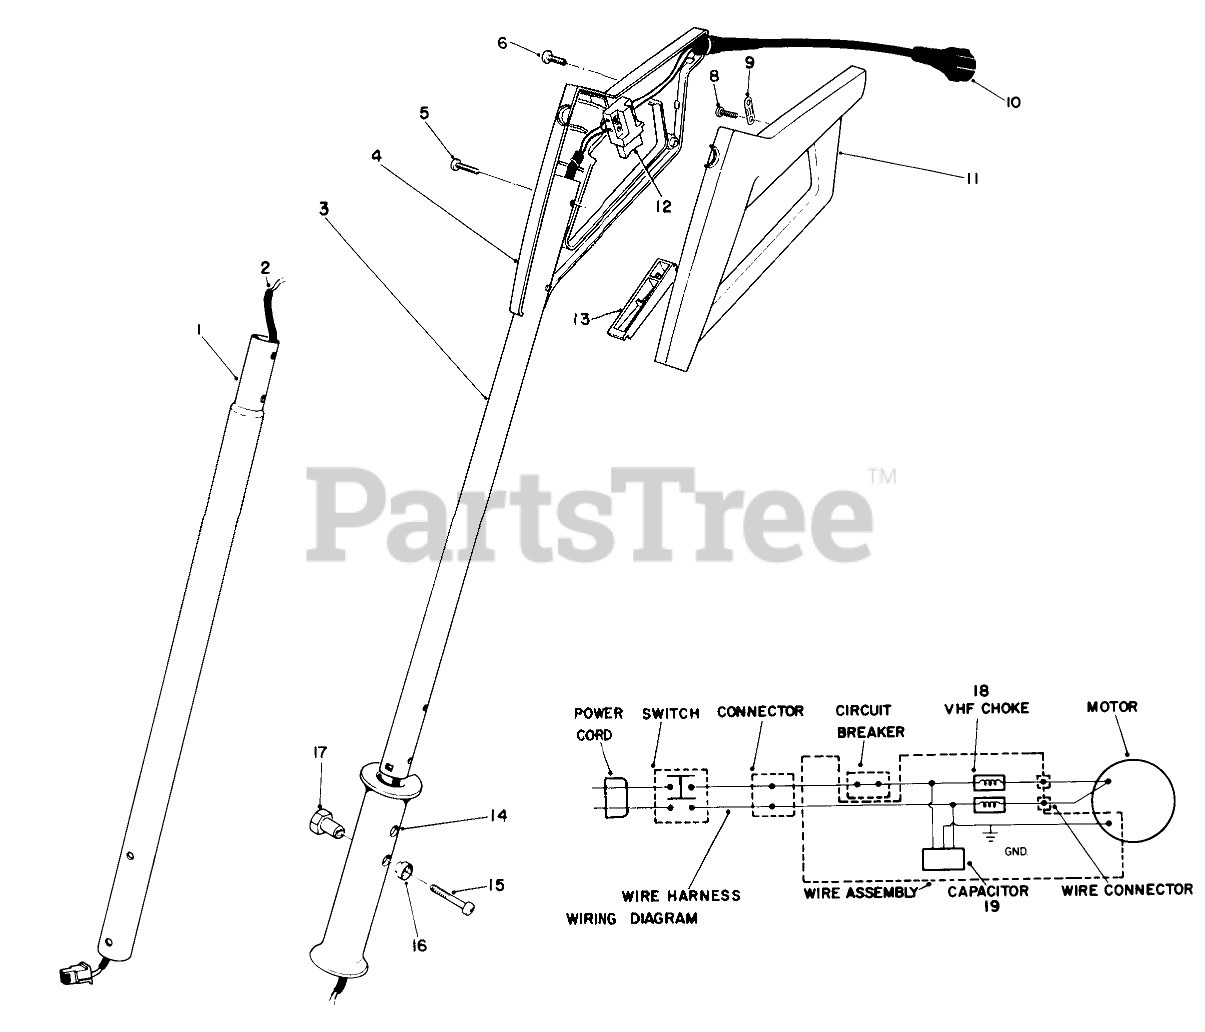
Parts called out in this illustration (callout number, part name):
1	LOWER TUBE, P. SHOVEL
2	Wire Harness
3	Tube-Upper Handle
4	Grip-Control R.H.
5	Screw
6	SCREW-PPH
8	Screw, Pan Head
9	Clamp-Power Cord
10	Power Cord-Upper Wiring Harness
11	Grip-Control L.H.
12	Switch
13	Switch Bar
14	Grip-Handle
15	SPEC PAN HD SCREW
16	Bushing-Screw
17	SPECIAL HEX NUT
18	VHF Choke
19	Capacitor
